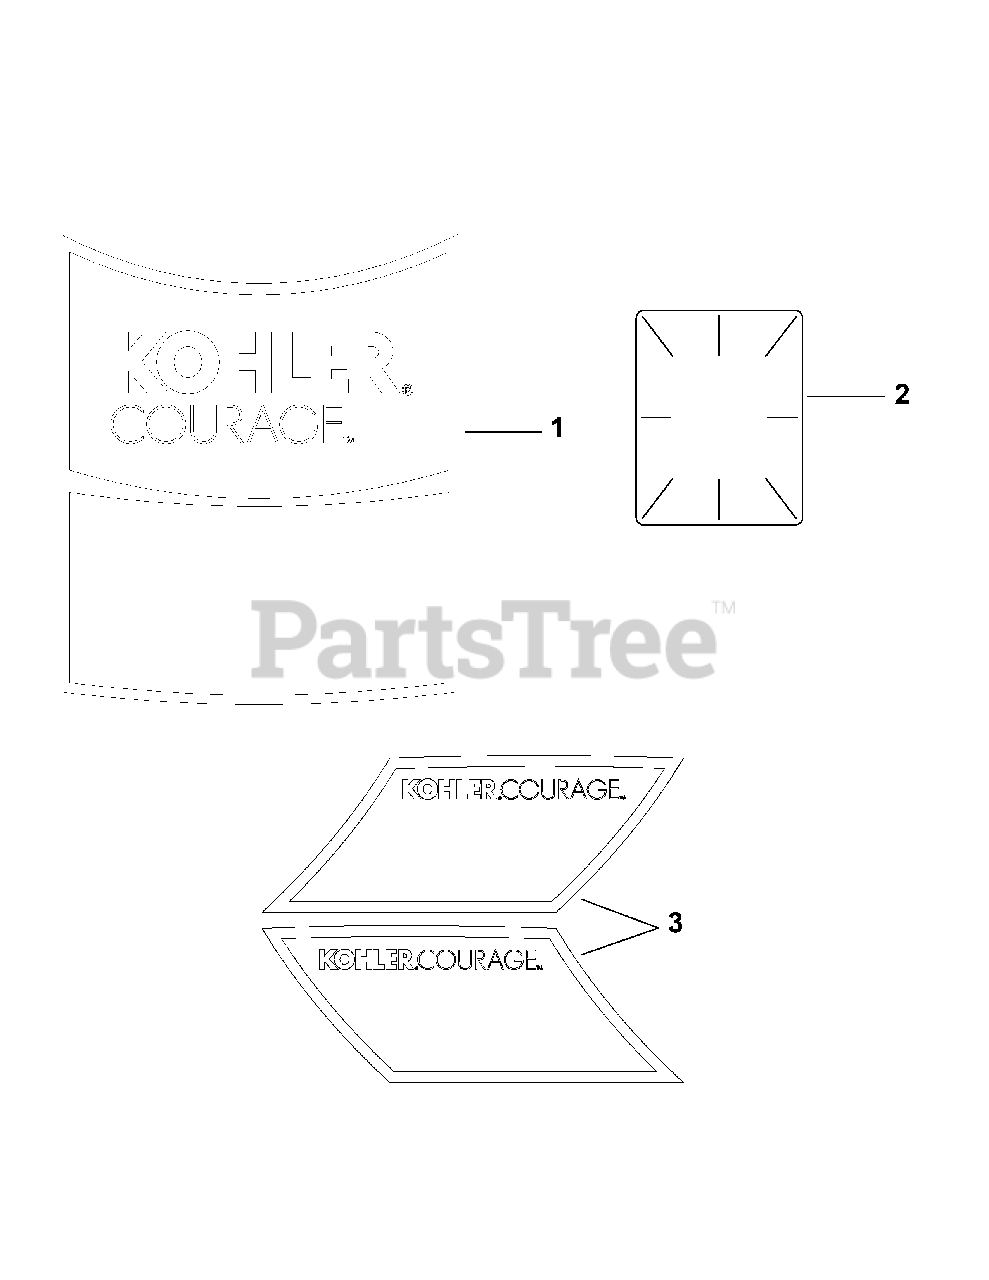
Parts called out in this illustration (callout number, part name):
1	20 HP Decal
2	Clear Lamination Decal
3	Cub Cadet Decal (2-pc Wing Set)
